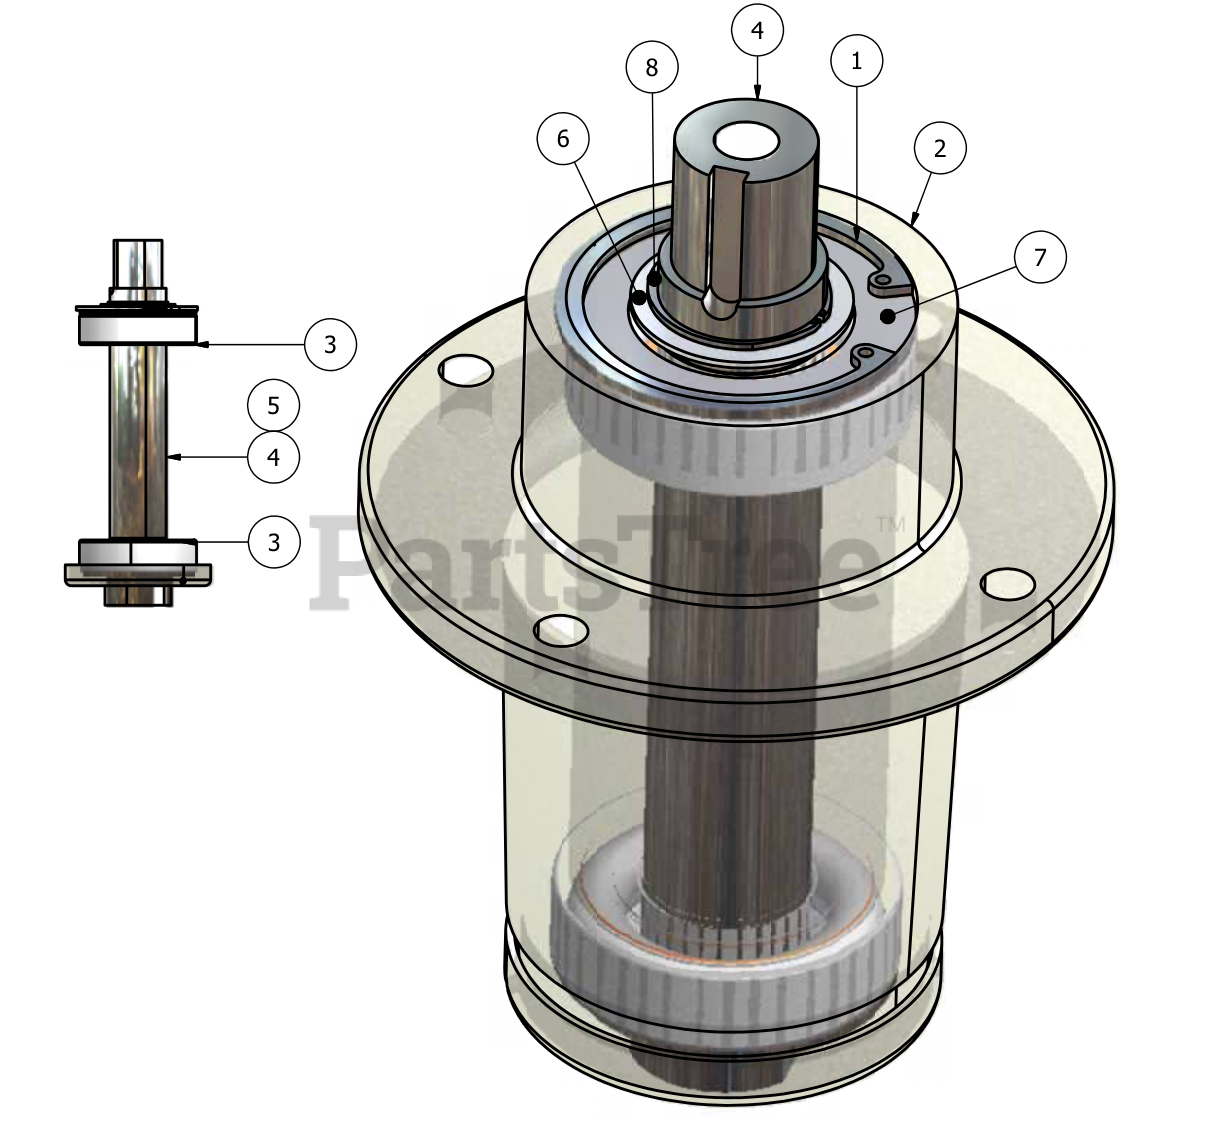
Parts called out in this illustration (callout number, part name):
1	Bearing Retainer Ring
2	Spindle Housing
4	Short Shaft
5	Long Shaft
6	Small Bearing Spacer
7	Large Bearing Spacer
8	Shaft Retainer Ring
